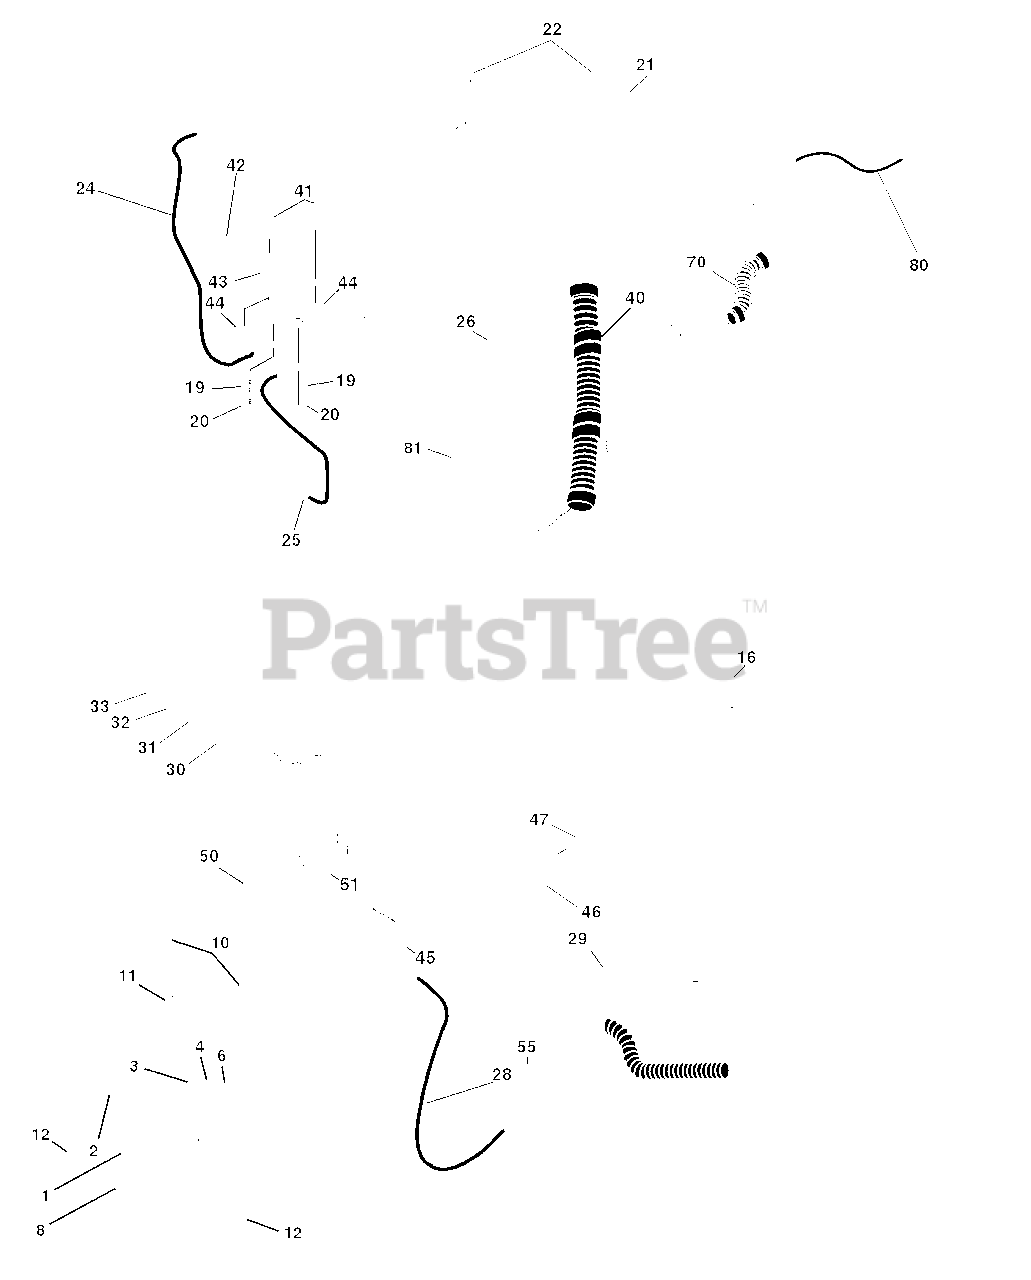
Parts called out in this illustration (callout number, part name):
1	Battery 12 Volt 35 AMP
2	Bolt Hex Hd 1/4-20unc X 3/4
3	Washer 9/32 X 5/8 X 16 Ga.
4	Washer Lock Hvy Helical 1/4
6	Nut Fin Hex 1/4-20 Unc
8	Case Battery Mech Hinge
10	Bolt Brt Frt 1/4-20 x 75 Ainc
11	Holddown Battery Front Mount
12	Nut Push Nylon 1/4" Battery Frt
16	Switch Interlock Push-In
19	Washer Lock 1/4
20	Nut Jam Hex 1/4-20 Unc
21	Harness Asm Light W/4152j
22	Bulb Light #1156
24	Cable Battery 6 Ga 11" red
25	Cable Battery 6 Ga 22" red w/16 wire
26	Fuse 30 AMP Auto Green
28	Cable Ground 6 Ga 21" black
29	Switch Plunger Nc Gray
30	Switch Ign 4 pos w/lights
31	Nut Ignition
32	Cover Sw Ignition
33	Key Ign Modelled Generic
40	Harness Ign.
41	Bolt Blk Fin Hex 1/4 - 20 x 1/2
42	Cover Terminal Red
43	Solenoid
44	Nut Keps Hex 1/4-20 Unc
45	Ammeter Rectangular 15 Amp
46	Meter Hour
47	Screw 10-24 x 1/2 Black
50	Switch PTO 3 PDT Black Delta 96
51	Ring Retainer TTO
55	Screw Thdrol 5/16-18 x 1-1/2 Tyt
70	Harness, Eng.
80	Harness Clutch Evx
81	Relay Asm.
